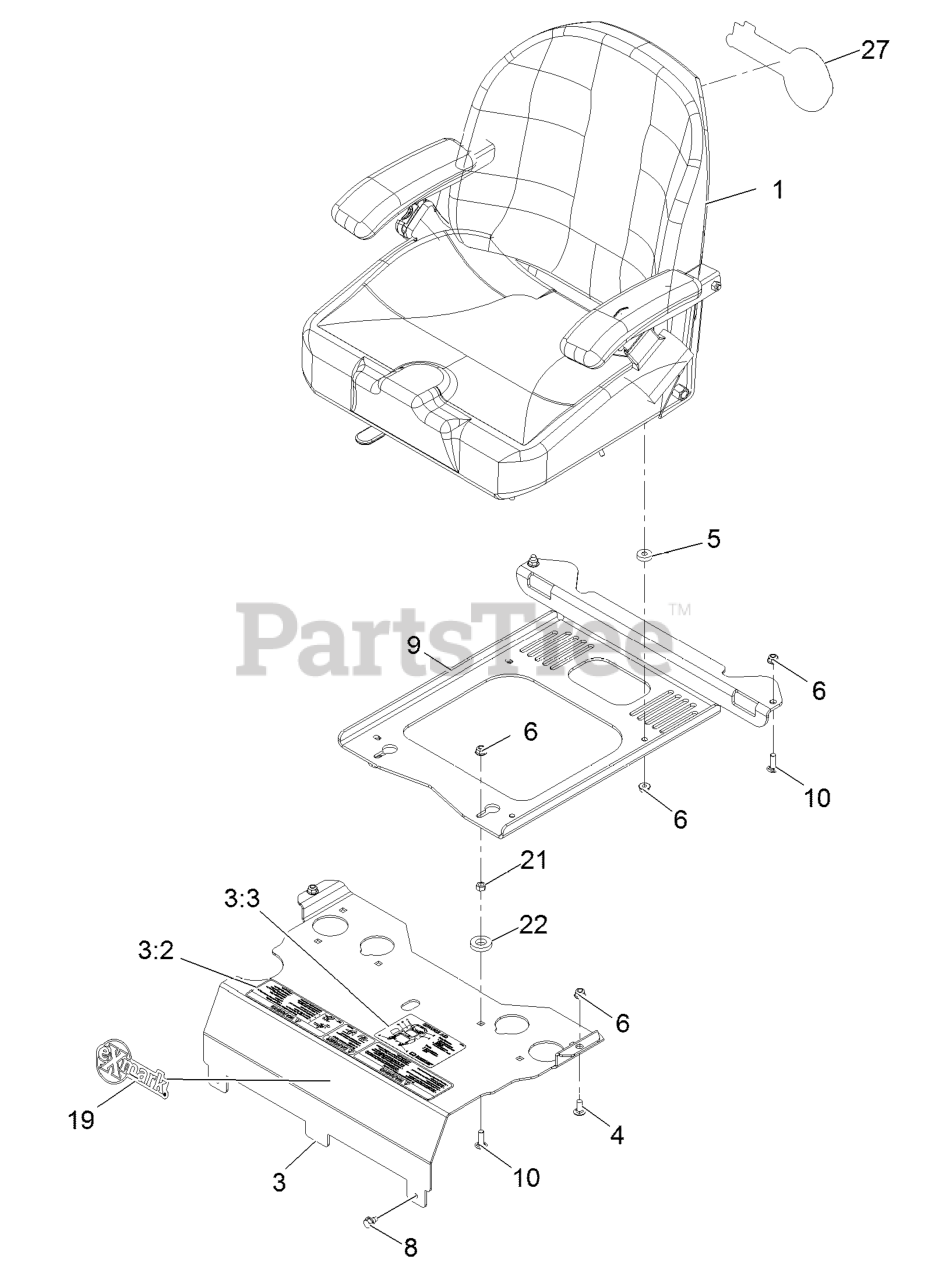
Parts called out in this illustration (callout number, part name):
1	ASM-SEAT, LZE
3	MOUNT-SEAT
3:2	DECAL-CONSOLE
3:3	DECAL-SERVICE AID
4	SCREW-CARR
6	NUT-HF, NI
9	PLATE-SUPPORT, SEAT
10	SCREW-CARR
21	NUT-HEX
27	DECAL,EXMARK LOGO
